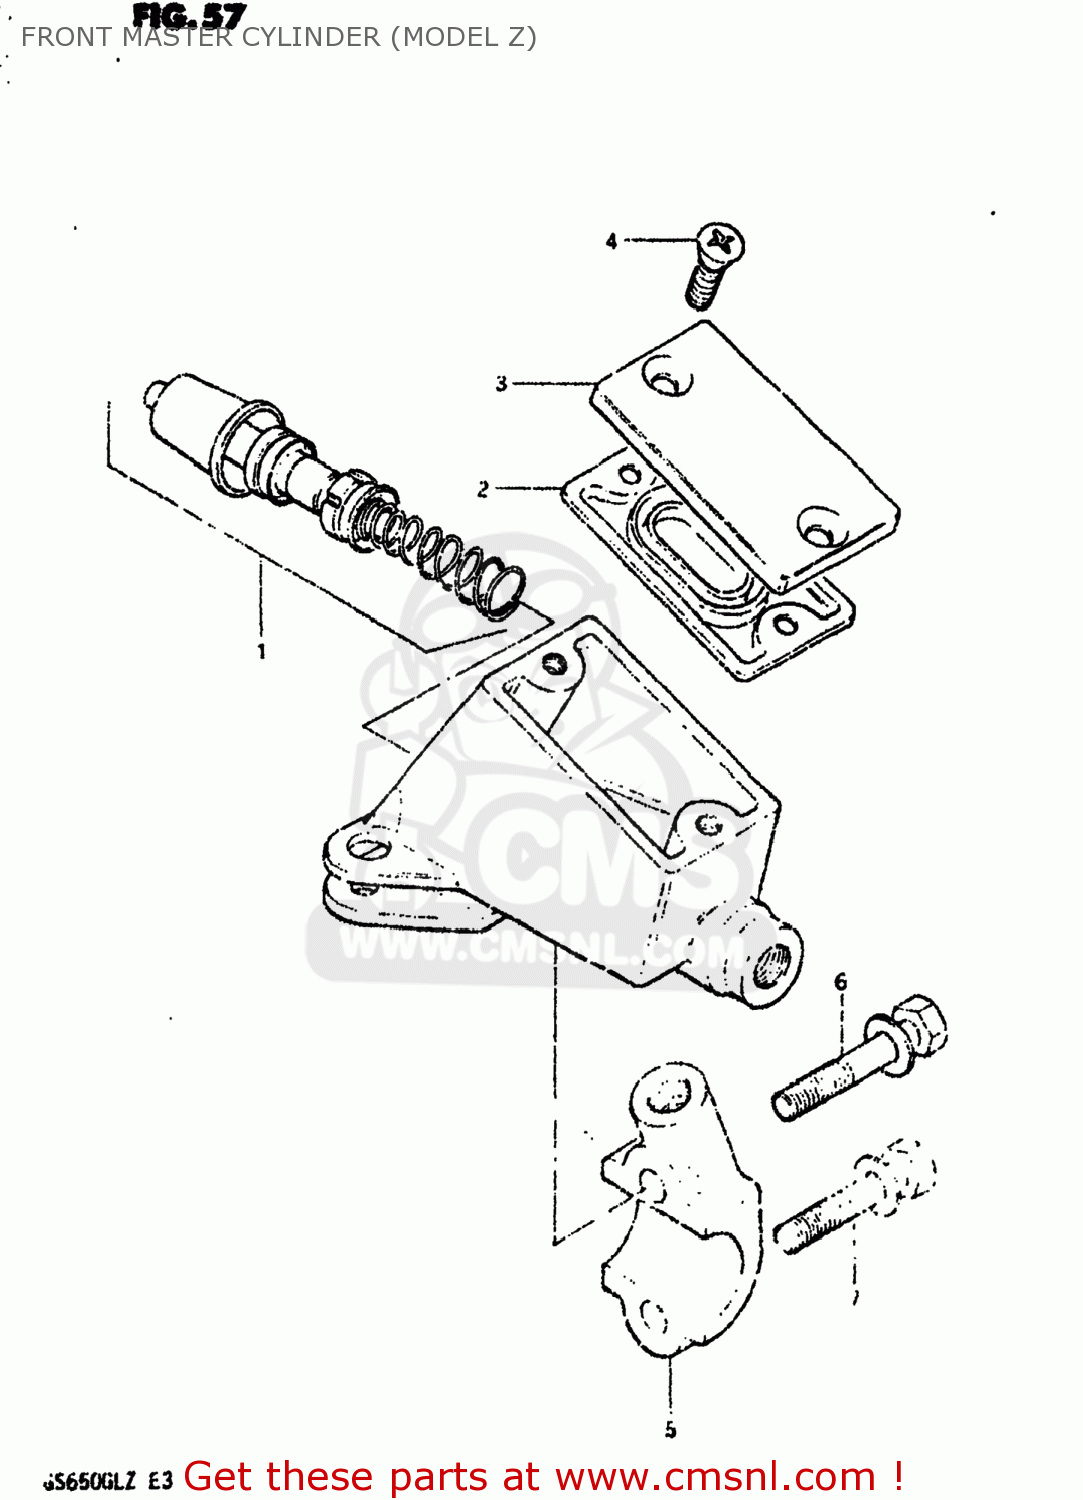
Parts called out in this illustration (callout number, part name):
1	PISTON & CUP SET
2	DIAPHRAGM,MASTER CYLINDER
3	CAP,MASTER CYLINDER,REAR
4	SCREW,RESERVOIR CAP
5	HOLDER,MASTER CYLINDER
6	BOLT,MASTER CYLINDER H
7	BOLT,MASTER CYLINDER H
